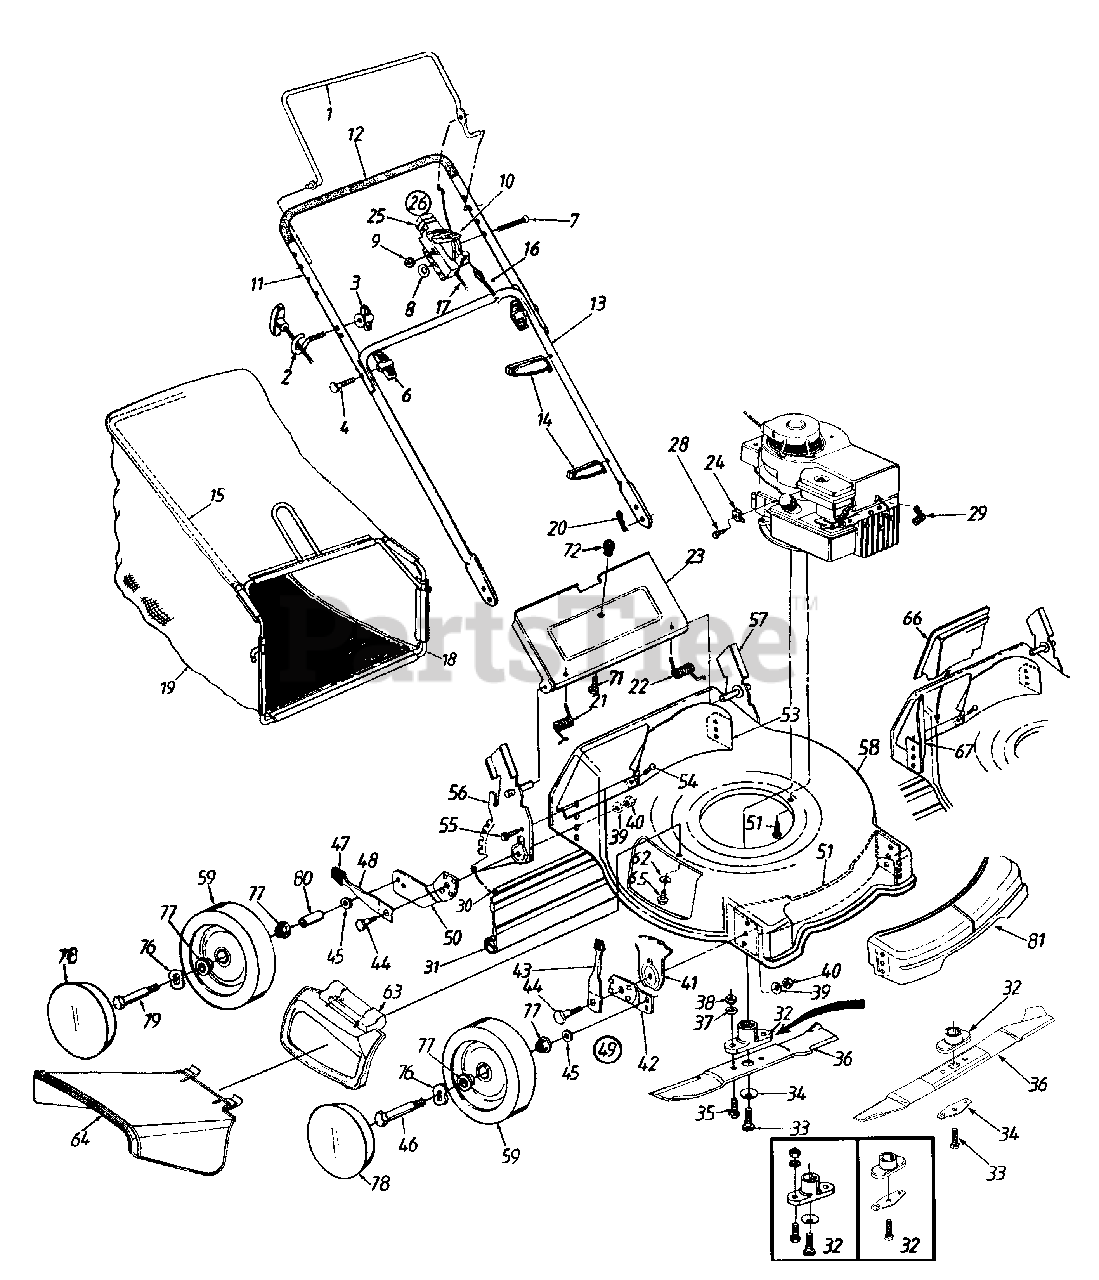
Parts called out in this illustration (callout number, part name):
2	Rope Guide
3	Handle Knob 1/4-20 Thd.
4	Curved Hd. Bolt 5/16-18 x 2" Lg.
6	Hand Knob
7	Oval C-Sunk Mach. Scr.
8	Spr. Wash. .66" I.D.
9	Hex L-Nut 1/4-20 Thd.
10	Throttle Lever
14	Cable Tie
16	Control Cable--36"
17	Throttle Control Wire--55"
20	Int. Cotter Pin 5/16" Dia.
21	Door Spring--R.H.
22	Door Spring--L.H.
25	Throttle Body
26	Throttle Box Comp.
28	Hex Wash. Hd. Scr. #10-32 x .62" Lg.
29	Spark Plug Boot
30	Wire Rod
31	Rear Flap
32	Blade Adapter Kit
33	Hex Bolt 3/8-24 x 1.5" Lg.
34	Blade Bell Support
35	Hex Bolt 3/8-24 x 1" Lg.
36	21" Mulching Blade
37	L-Wash. 3/8" I.D.
38	Hex Nut 3/8-24 Thd.
39	Bell-Wash. .39" I.D. x 1.38"
40	Hex Nut 3/8-16 Thd.
41	Height Adj. Plate
43	Spring Lever Ass'y. w/Knob
44	Shld. Bolt .5" Dia. x .357"
45	Bell-Wash. .38" I.D. x .88" O.D.
46	Front Axle Bolt
47	Spring Lever Knob
48	Spring Lever
49	Height Adj. Ass'y. Comp.--R.H.
50	Pivot Bar R.H.
54	Torx Mach AB-Tap Scr. 1/4 x .62" L.
55	HexIndWash. Scr. 1/4-14:.625
62	Bell-Washer 1/4" I.D.
63	Hinged Mulching Plug
64	Chute Deflector
65	Hex Hd Self-Tap Scr. 1/4-20 x .5" L.
71	Truss Scr. #10-24 x .38" Lg.
76	Wave Washer
77	Ball Bearings
78	Hub Cap
79	Rear Axle Bolt
80	Spacer
81	Cover- Front End
